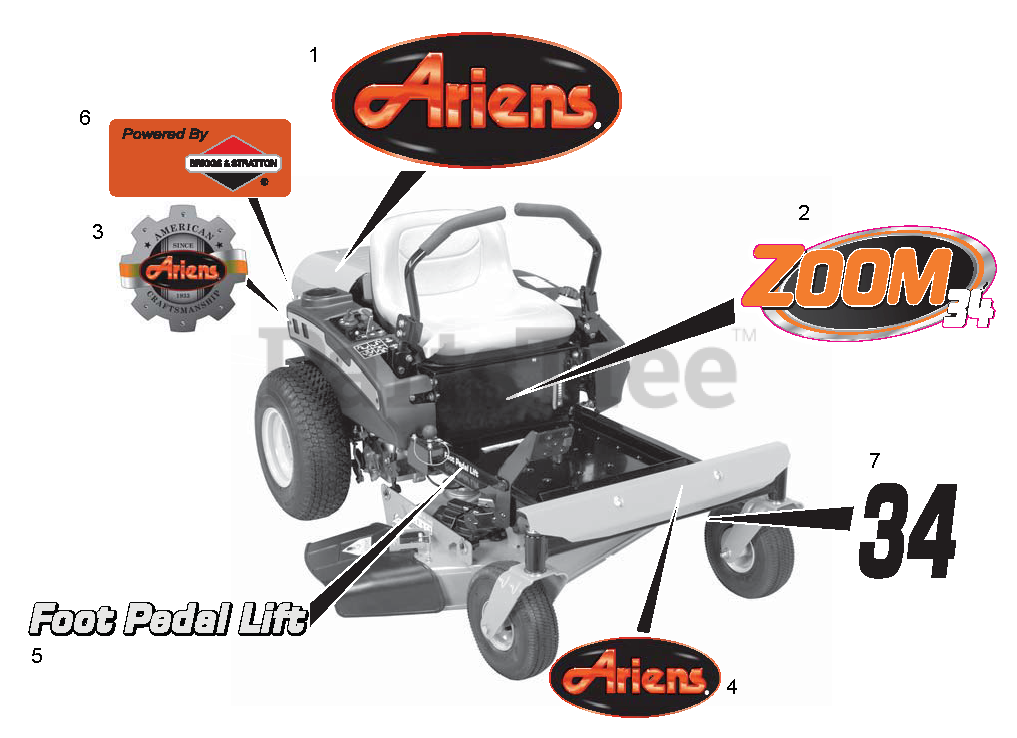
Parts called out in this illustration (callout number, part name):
1	DECAL, ARIENS JEWEL
2	DECAL, ZOOM 34
3	Decal, Ariens Heritage, Large
4	DECAL. ARIENS DOMED JEWEL
5	DECAL, FOOT PEDAL LIFT
6	DECAL, POWERED BY B&S
7	DECAL, DECK SIZE, 34"
